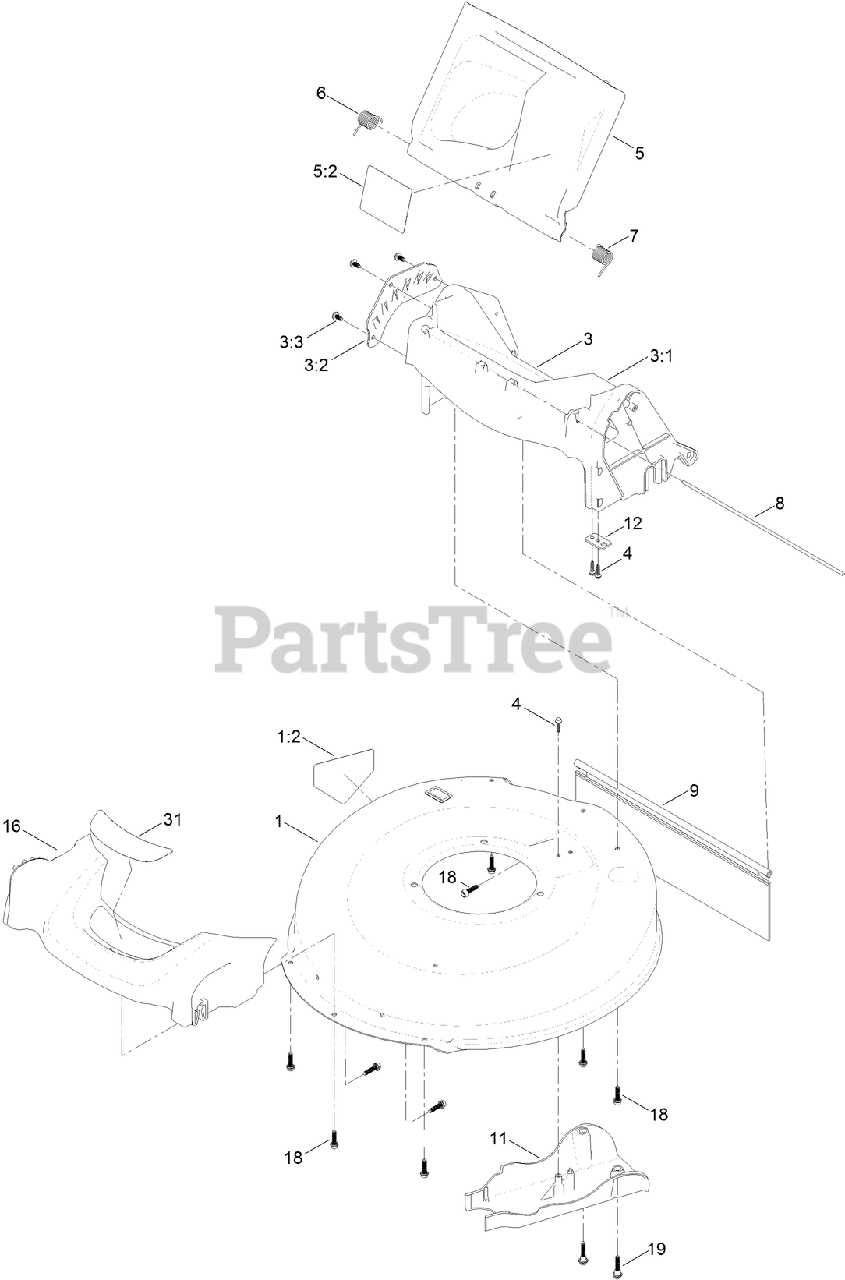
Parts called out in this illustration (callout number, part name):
1	HOUSING ASM
1:2	DECAL-DANGER
3	CHUTE ASM
3:1	CHUTE
3:3	SCREW-PLASTIC TPH
4	SCREW-HWH
5	REAR DEFLECTOR ASM
5:2	DECAL-WARNING
6	SPRING-TORSION
7	SPRING-TORSION
9	SHIELD-TRAILING
11	COVER-BELT
12	BRACKET-CABLE
18	SCREW-FLANGE, PLASTIC
19	SCREW-SHOULDER, HHF
31	DECAL-DECK
